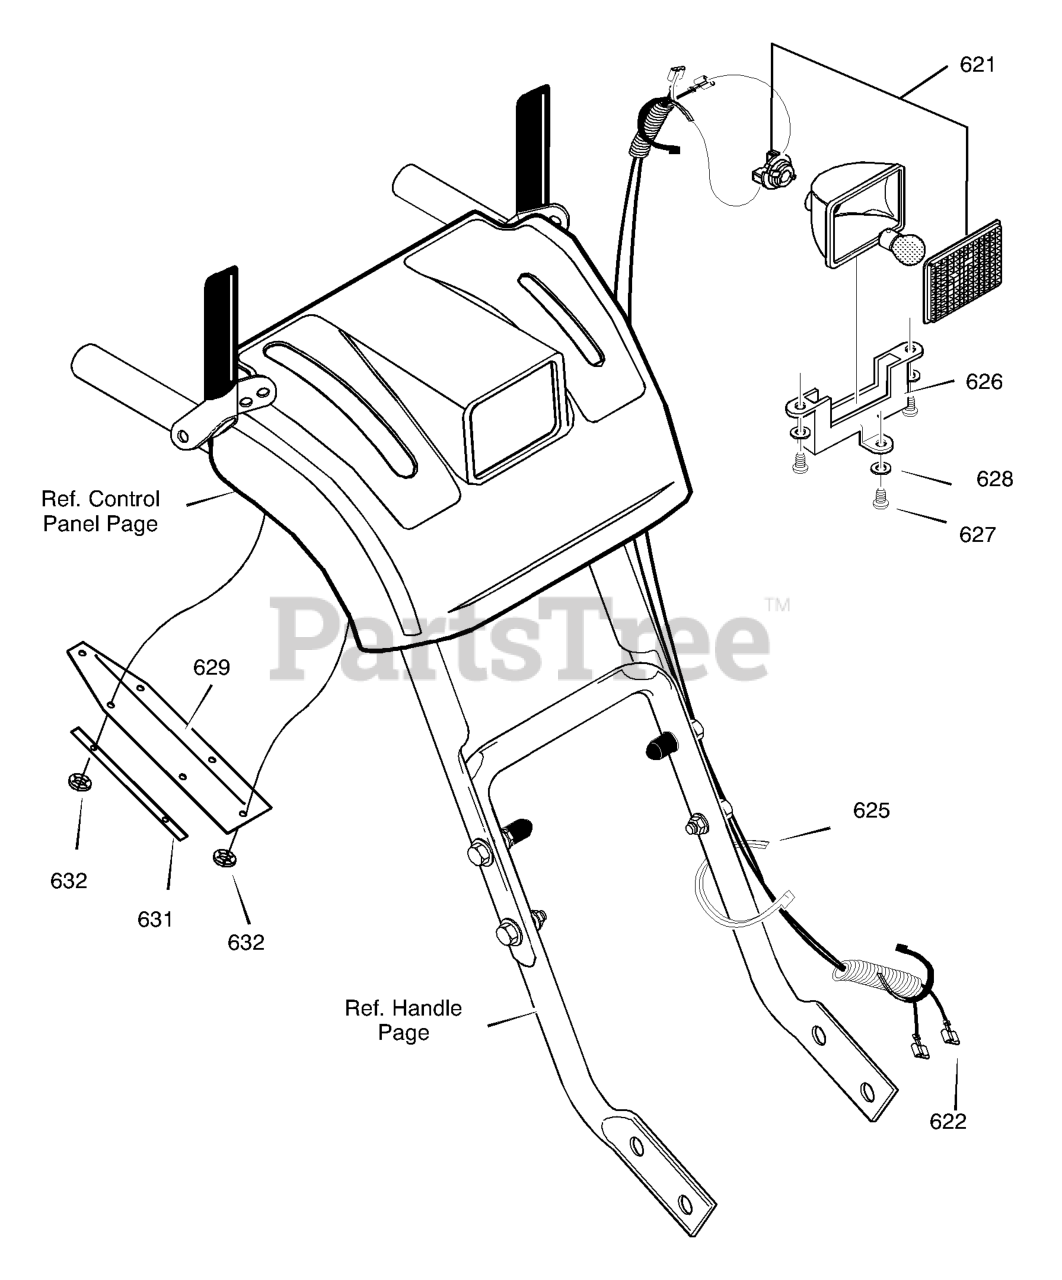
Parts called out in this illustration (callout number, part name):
621	LIGHT, HALOGEN
622	HARNESS, WIRE
625	TIE, CABLE
626	BRACKET, LIGHT
627	SCREW #8 X .50
628	WASHER, FLAT
629	COVER, SPEED LEVER
629	COVER, CHUTE LEVER
630	FRAME, SPEED LEVER
632	NUT, PUSH
